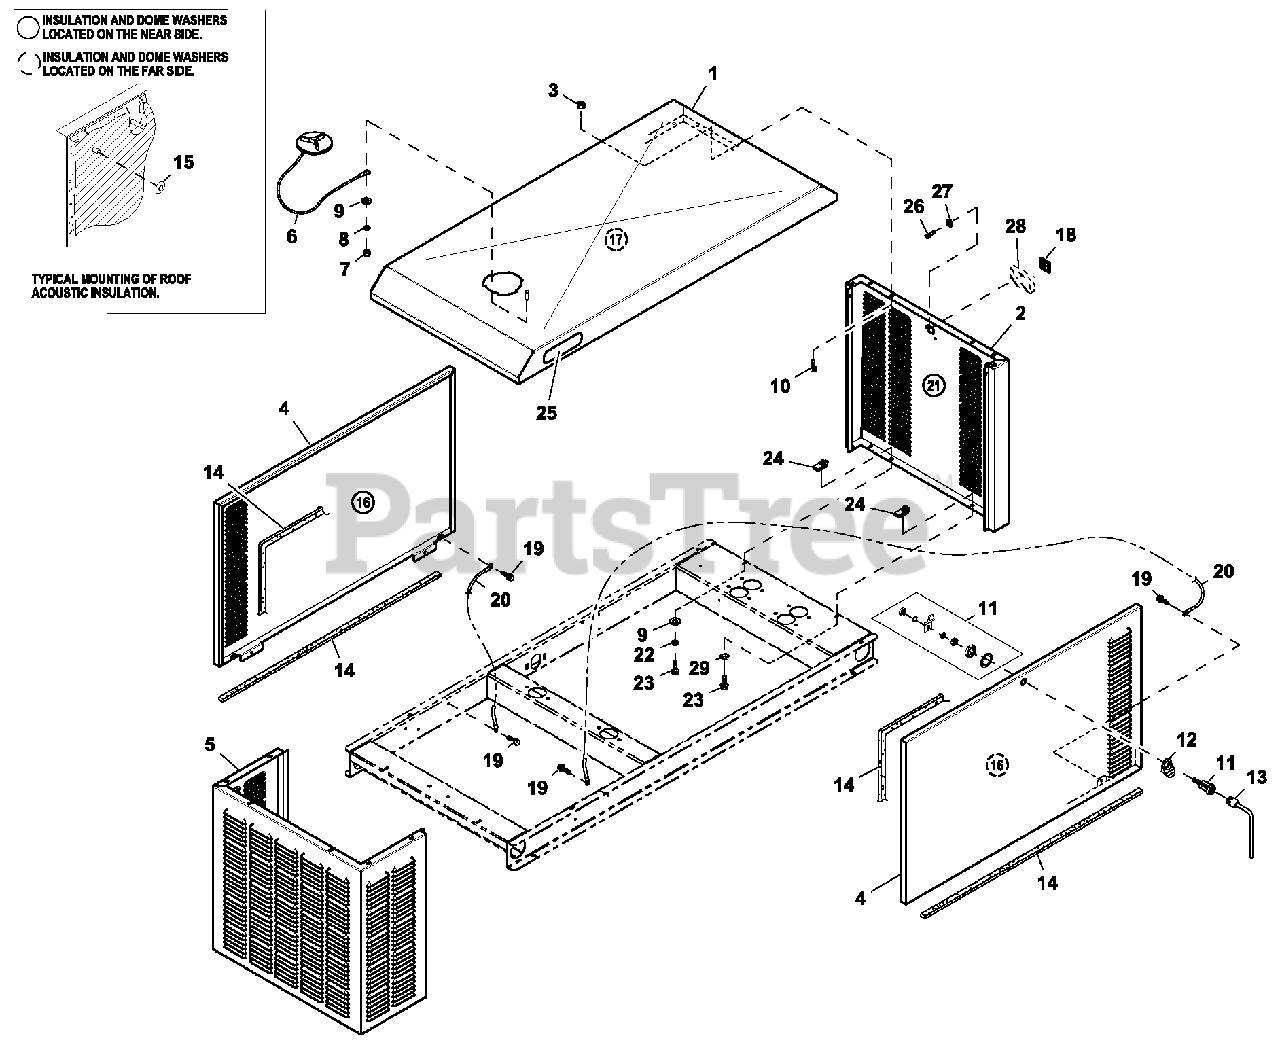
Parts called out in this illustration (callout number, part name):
1	ROOF C1 CPL PVT LBL
2	REAR INTAKE WRAP C1
3	NUT HEX LOCK M 6-1.0 SS NY INS
4	DOOR LEFT/RIGHT SIDE C1
5	FRONT DISCHARGE WRAP 1.6L C1
6	ASSY ACCESS COVER
7	NUT HEX 1/4-20 STEEL
8	WASHER LOCK M6-1/4
9	WASHER FLAT 1/4-M6 ZINC
10	SCREW THF M6-1 X 16 N WA Z/JS
11	VISE-ACTION LATCH, SLOTTED CIR
12	PULL TAB DOOR LOCK SS
13	KEY VISE-ACTION LATCH,SLOT CIR
14	FOA M STRIP 3/4"WIDE X 3/16"THK (294"LG)
15	WASHER SELF LOCKING DO ME
16	INSULATION SIDE DOOR C1
17	INSULATION ROOF C1
18	RF COVER PLATE-PLASTIC-DRK GRY
19	SCREW HWHTFM 6-1.0X16
20	ASSY WIRE 14AWG GRN/YEL (32.25"LG)
21	INSULATION REAR C1
22	WASHER LOCK M6-1/4
23	SCREW HHFC M 6-1.0X20 G8.8
24	NUT SPRINGCLIP M 6-1.0
25	BADGE, HONEYWELL
26	SCREW PPPH M3X12
27	WASHER FLAT M3
28	ASSY ENCLOSURE GEN SIDE RF
29	WASHER LOCK SPECIAL 1/4"
